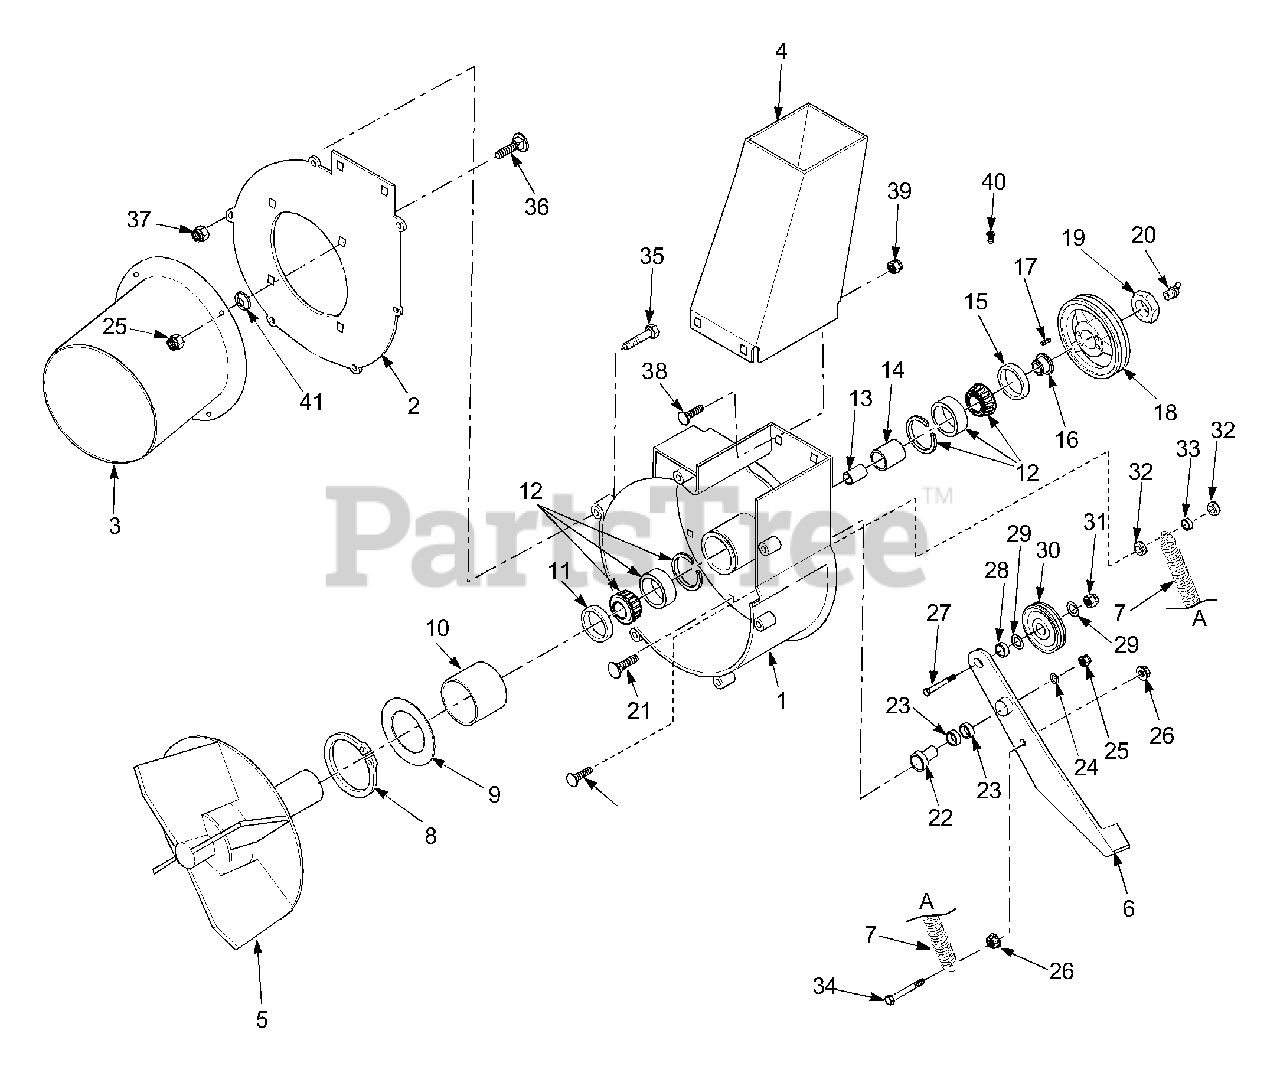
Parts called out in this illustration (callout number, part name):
1	Blower Housing, Rear
2	Blower Housing, Front
3	Inlet
4	Outlet
6	Idler Arm, Weldment
7	Spring
8	Ring, Retaining 2.5 ext.
9	Washer, Retainer
10	Bushing, Oilite 2.505 ID
11	Seal, 2.00 OD x 1.50 Bore
12	Bearing Assembly
13	Spacer, Inside
14	Spacer, Outside
15	Seal, 2.00 OD x 1.625 Bore
16	Bushing
17	Key, 1/4 x .874 Woodruff
18	Pulley, 5.25 OD
19	Nut, 1-1/16 - 18 LH Thread
20	Grease Fitting, 65 degree angle
21	Bolt, Carriage 3/8-16 x 2.5"
22	Pivot, Idler Arm
23	Bearing
24	Flatwasher 3/8"
25	Nut, Elastic Stop 3/8-16
26	Nut, Serr. Flng. 3/8-16
27	Bolt, HH 3/8-16 x 2.25"
28	Spacer
29	Flat Washer 3/8"
30	Pulley, 3.0" diameter
31	Nut, Elastic Stop 3/8-16
32	Nut, Serr. Flng. 3/8-16
33	Spacer
34	Bolt, HH 3/8-16 x 1.5"
35	Bolt, HH 5/16-18 x 1.5"
36	Bolt, Carriage 3/8-16 x 1.0
37	Nut, Elastic Stop 5/16-18
38	Bolt, Carriage 1/4-20 x 1.0
39	Nut, Elastic Stop 1/4-20
40	Relief Fitting
41	Push Nut, 3/8 Thread
